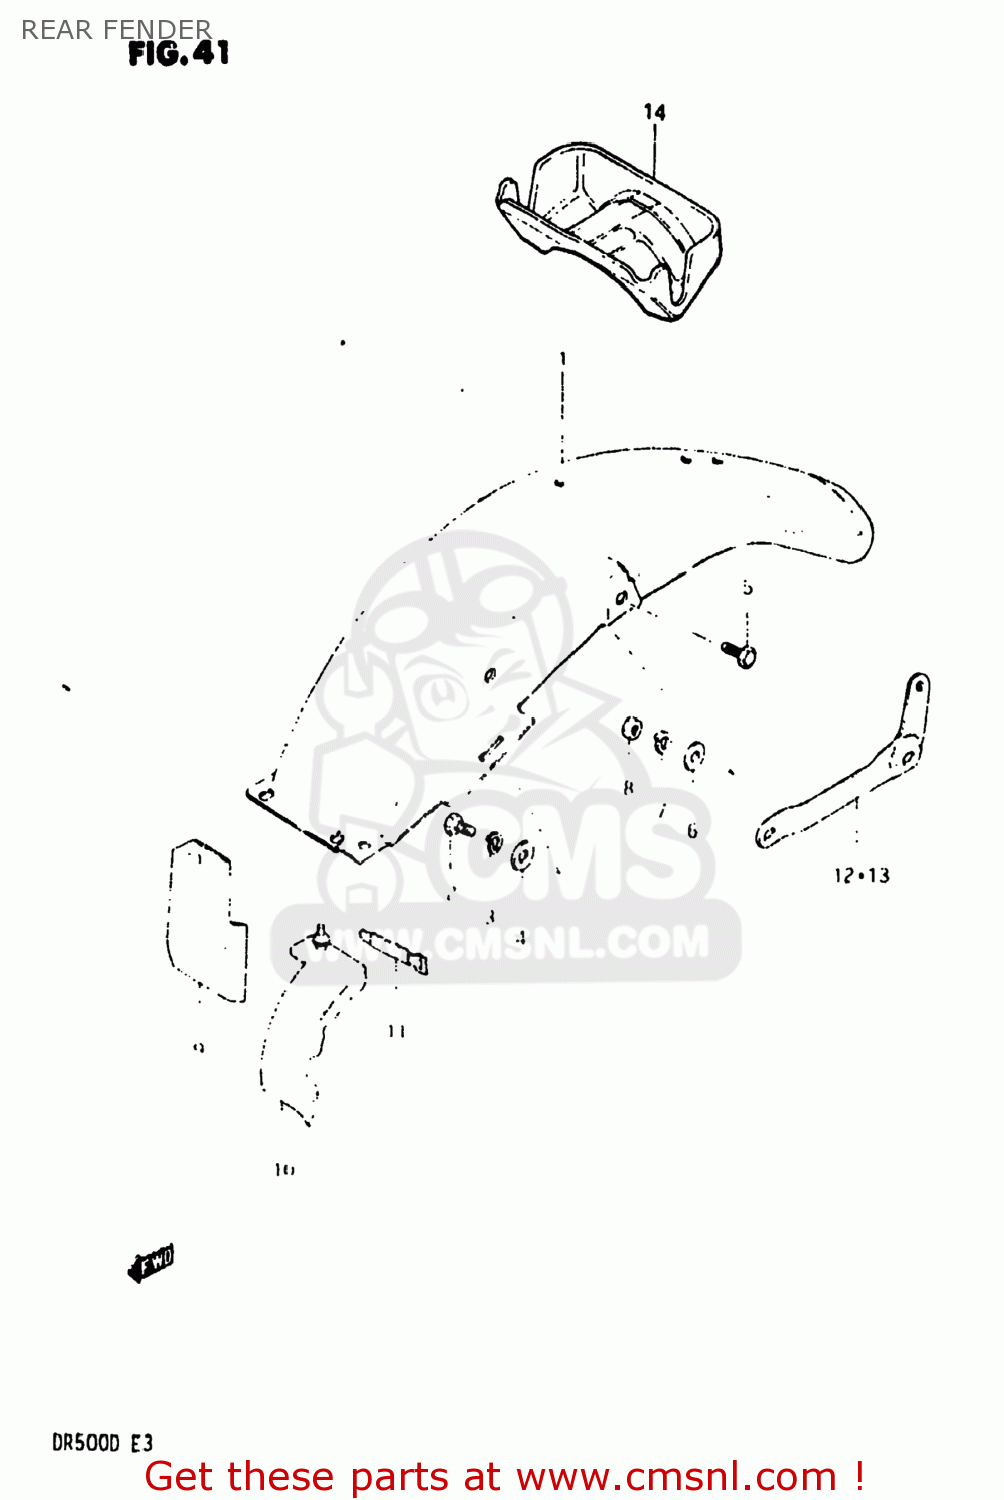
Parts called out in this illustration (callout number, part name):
1	FENDER,REAR
2	BOLT
3	LOCK WASHER
4	WASHER (8.2X20X1.6)
5	BOLT
6	WASHER (8.2X20X1.6)
7	WASHER,LOCK,8.
8	NUT
9	MUD GUARD,REAR FENDER
10	MUD GUARD,REAR FENDER
11	CLAMP L:110
12	REINFORCEMENT,REAR FENDER
13	REINFORCEMENT,REAR FENDER
14	BAG ASSEMBLY,SEAT TAIL
